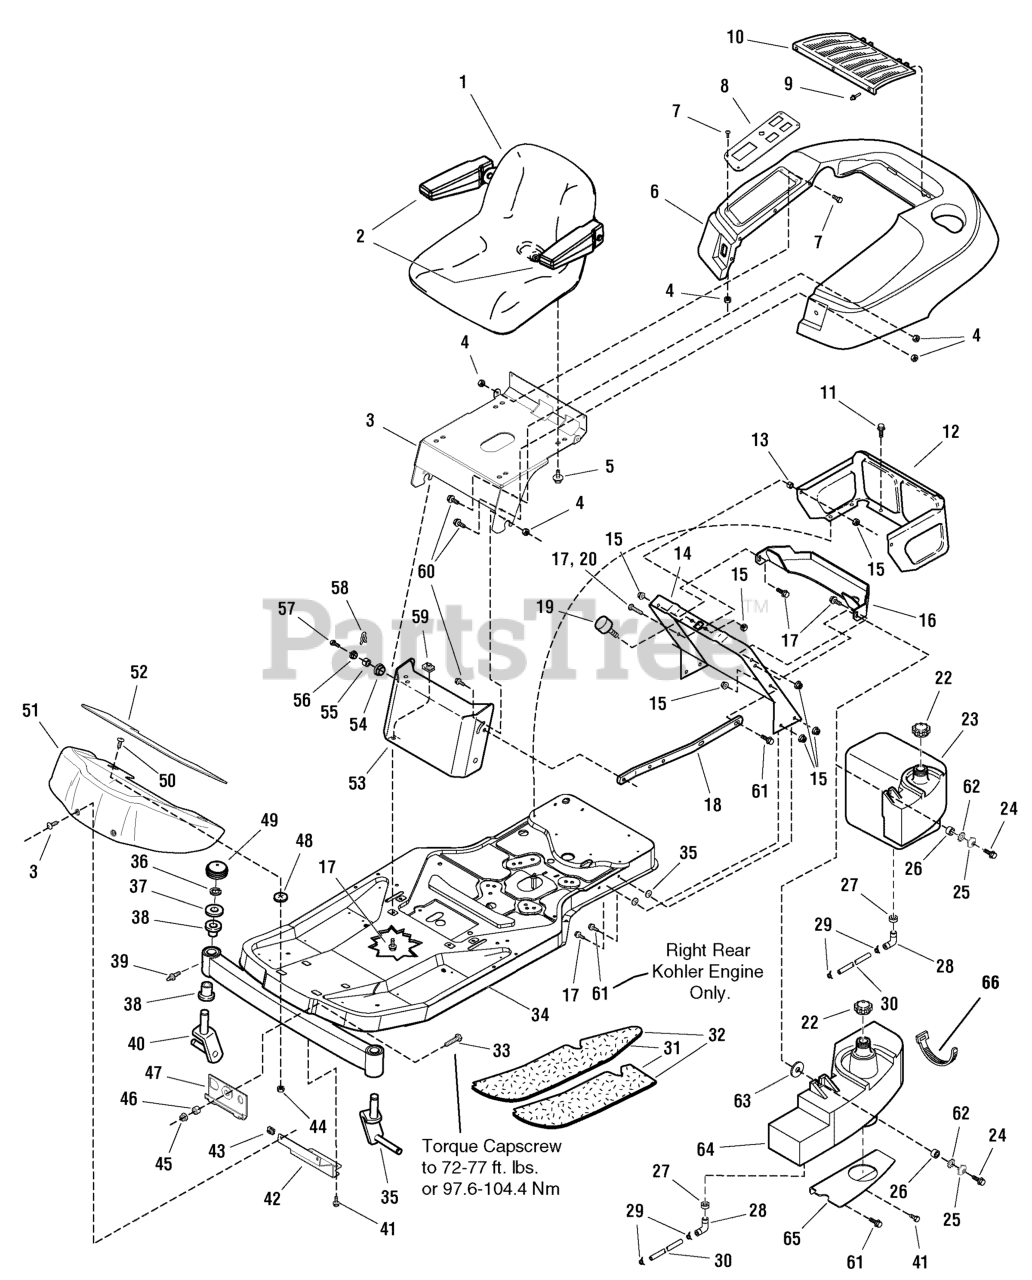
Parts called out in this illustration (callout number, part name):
1	SEAT ASSEMBLY, with Arm Rests
2	ARM REST KIT, (L.H. & R.H.)
3	SUPPORT, Seat
4	NUT, Hex Flange ESNA, 1/4-20
5	CAPSCREW, Hex Head Whiz Lock Dog Point, 5/16-18 x 3/4
6	DECK, Seat
7	SCREW, Truss Head Torx Drive, 1/4-20 x 3/4
8	PLATE, Pod Control
9	RIVET, Pop
10	SCREEN, Seat Deck
11	CAPSCREW, Hex Washer Head Taptite, 1/4-20 x 1/2
12	SHROUD, Rear
14	SUPPORT, Seat Deck
15	NUT, Hex Flange Whiz Lock, 5/16-18
16	DUCT, Air Inlet
17	CAPSCREW, Hex Head Whix Lock, 5/16-18 x 3/4, G5
18	BRACE, Tank
19	BUMPER, Rubber
20	SCREW, 5/16-18 x 1-1/2, Hex Flange, Whiz Lock
21	NUT, Push
22	CAP, Fuel Tank
24	CAPSCREW, Hex Washer Head Taptite, 5/16-18 x 1-1/2
25	WASHER, 5/16
27	BUSHING, Fuel Tank
28	ELBOW, with Screen, Gas Tank to Fuel Line
29	CLAMP, Hose, Wire Type E
30	HOSE, Fuel 8.5" Long
31	PAD, Footrest, R.H.
32	PAD, Footrest, L.H.
33	CAPSCREW, Hex, 1/2-13 x 1-1/2
34	FRAME & SPINDLES ASSEMBLY
35	ARM, Caster, L.H.
36	RING, E-Retaining
37	WASHER
39	FITTING, Lube
40	ARM, Caster, R.H.
41	SCREW, Hex Washer Head Taptite, 5/16-18 x 3/4
42	BRACKET, Footrest Support
43	NUT, Speed Lug Type, 1/4-20
44	NUT, Hex Flange Whiz Lock, 1/4-20
45	NUT, Hex Flange, Two-Way Lock, 1/2-13
47	HOOK & WASHER ASSEMBLY
48	NUT, Push, 1/4
49	CAP, Hub
50	CARRIAGE BOLT, 1/4-20 x 3/4
51	PANEL, Footrest
52	PAD, Footrest, Front
53	PANEL, Front
56	PIVOT, Hood
57	PIN, Quick
58	CAPSCREW, Hex Washer Head Taptite, 5/16-18 x 1
59	NUT, Speed, Lug Type, 5/16-18
60	SCREW, Hex Flange Whiz Lock, 1/4-20 x 5/8
61	CAPSCREW, Hex Flange Whiz Lock, 5/16-18 x 1-1/4, G5
62	LOCKWASHER, External Tooth, 3/8
63	WASHER, 3/8 x 1-1/4 x 1/4
64	TANK, Fuel
65	BRACKET, Fuel Tank
66	TIE, Self-Locking
